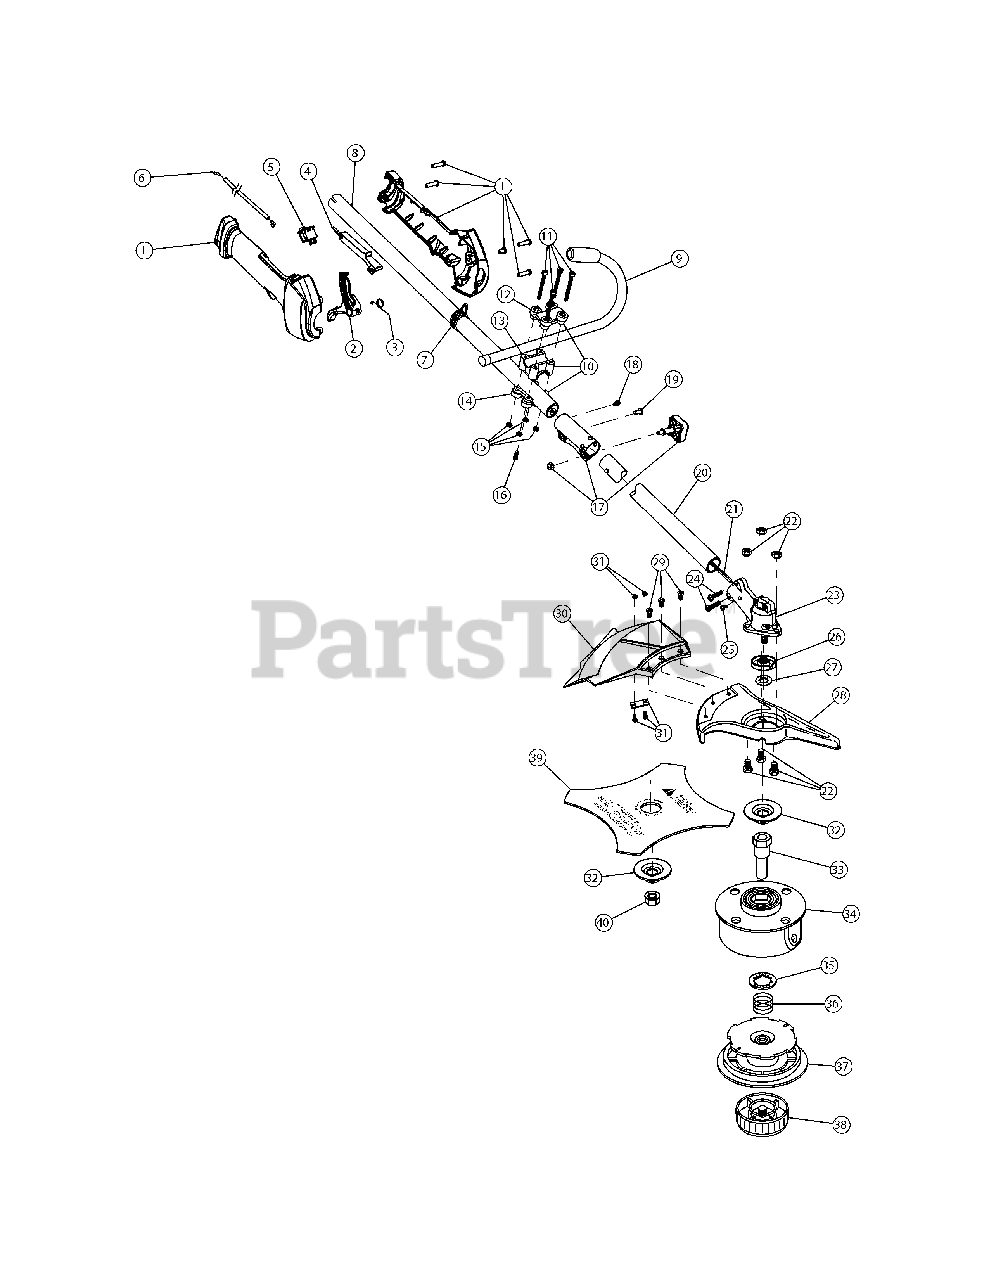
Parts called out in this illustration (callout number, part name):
1	Throttle Housing Assembly
2	Throttle Trigger
3	Throttle Trigger Spring
4	Throttle Trigger Lock-Out
5	Switch Assembly
6	Throttle Cable Assembly
7	Harness Clip
8	Upper Drive Shaft Housing Assembly
9	J-Handle Assembly
10	Handle Bracket Assembly
12	Upper Handle Clamp
13	Middle Handle Clamp
14	Lower Handle Clamp
16	Anti-Rotation Screw
17	Split Boom Coupler
20	Lower Drive Shaft Housing Assembly
21	Lower Flexible Drive Shaft
22	Shield Mount Screw Assembly
23	2 piece Gearbox Assembly
24	Gearbox Mounting Hardware
25	Anti-Rotation Screw
26	Blade Driver
28	Blade Shield/Shield Mount
29	Shield Mounting Screw
30	Shield Assembly
31	Blade Assembly
32	Retaining Washer
33	Spool Shaft
34	Outer Spool Assembly
35	Retainer
38	Bump Head Knob Assembly
39	4-Tooth Blade
40	Nut
